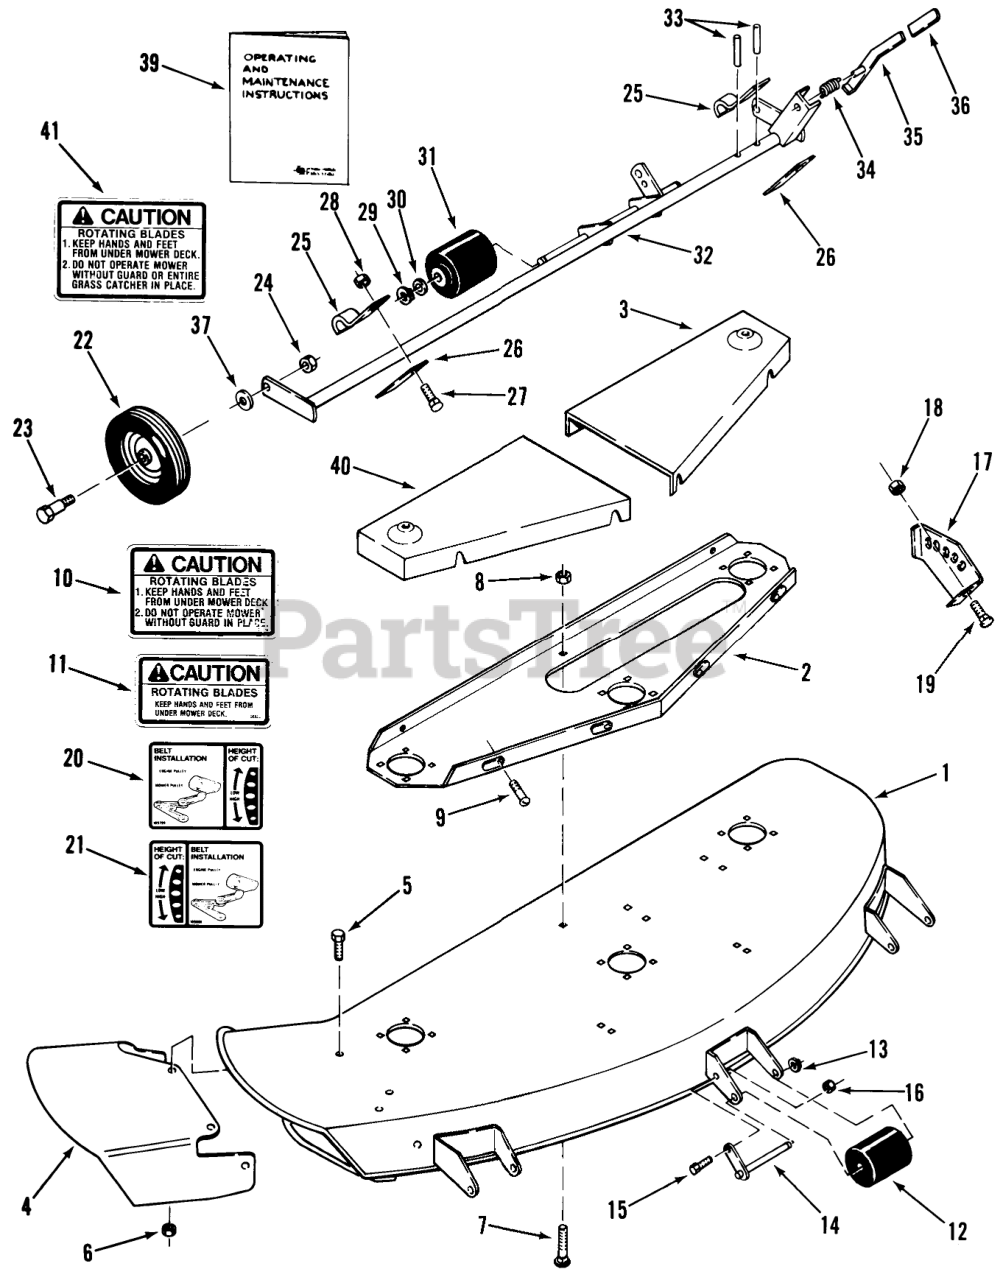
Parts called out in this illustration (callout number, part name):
1	ASSY-48 MOWER DEC R
1	ASSY DECK 42"MOWE R
2	Channel
3	Belt Cover LH
4	Chute Extension
5	Bolt
6	Nut
7	Bolt-Carriage
8	NUT
9	Screw
9	Bolt
10	Decal-Caution
11	Caution Decal
12	Roller
13	Retaining Ring
14	Roller Shaft
15	H H C S
16	Nut
17	LH QUADRANT R
17	Quadrant
18	NUT
19	Bolt
20	DECAL-HEIGHT & BELT
21	DECAL-HEIGHT & BELT
22	Wheel 6 x 1.75
23	BOLT-SHOULDER
24	Nut
25	Machine Bolt
26	Bar
27	Bolt
28	NUT
29	Retaining Ring
30	Washer
31	Roller
32	ASSY-GAGE WHEEL S R
32	WHEEL SUPPORT ASS R
33	PIN-SPIROL
34	SPRING-COMPRESSION
35	Lever
35	LEVER ASSY R
37	WASHER
39	Operating and Maintenance Instructions
40	Belt Cover RH
41	DECAL
